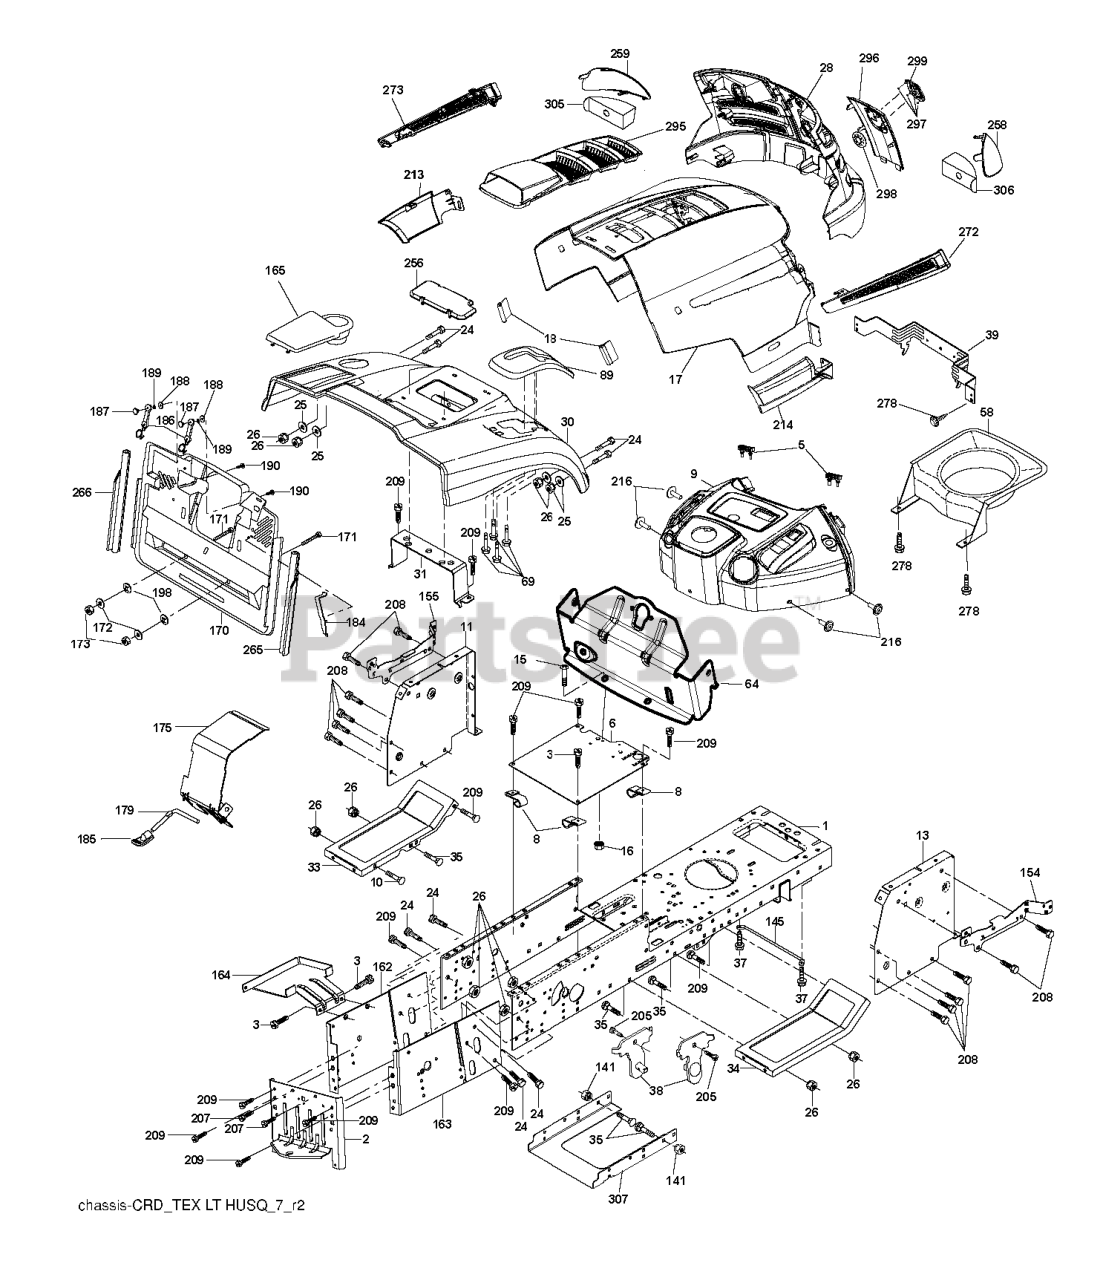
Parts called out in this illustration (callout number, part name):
2	DRAWBAR
3	SCREW 3/8-16X3/4
5	BUMPER DASH
6	PLATE
8	CLIP,INSULATOR
10	BOLT D
11	PANEL.DASH.LH.LTX
13	PANEL ASM, DASH RH
15	Screw, Machine, Truss Head 5/16-18 UNC x 3/4
16	NUT
17	HOOD.HUSQVARNA.LT.ORANGE
18	BUMPER.HOOD.TEX.HUSQVARNA
25	WASHER
26	NUT
28	RP GRILLE/LENS ASM.
30	CONSOLE.CRD.AUTO.GRY
31	BRACKET SUPPORT FENDER
33	FOOTREST PNT LH
34	FOOTREST PNT RH
37	Screw 5/16-18 x 1/2 Hex, Self Tapping 5/16-18 x 1/2
38	BRACKET ASM PIVOT MOWER REAR
39	BRACKET PIVOT
69	SCREW.HI-LO.CONSOLE
89	CONSOLE.CRD.AUTO.GREY.2005
141	NUT LOCK FLG 3/8-16 UNC
145	ROD.PIVOT.HOOD
162	BRACKET
163	BRACKET EXTEN CHASSIS RH CRD
165	RP.COVER.BATTERY.CRD.GREY
172	WASHER
175	DOOR TRAP
179	ROD PIVOT FBI
184	BRACKET.ACTUATOR.BAGGER.SRD
186	LATCH ASSY
187	WELDNUT
189	LOCKWASHER #10
190	SCREW
207	SCREW, 5/16-18 X 1/2
208	SCREW 3/8-16X1/2
209	SCREW, 3/8-16X3/4
213	SKIRT SIDE LH
214	SKIRT SIDE RH
216	SCREW HEXWSHR 1/4-20X3/4
256	COVER FENDER CRD
258	LENS.HUSQVARNA LT.RH
259	LENS.HUSQVARNA LT.LH
265	SEALING
266	SEALING
272	VENT SIDE HOOD RH
273	VENT SIDE HOOD LH
278	SCREW.#10 X 0.750.BOS
295	VENT TOP HOOD
296	TRIM
297	CLIP.RETAINER.TINNER.
298	NUT PUSH M
299	RP LOGO
305	INSERT REFLECTIVE
306	INSERT.REFLECTIVE.RH.
